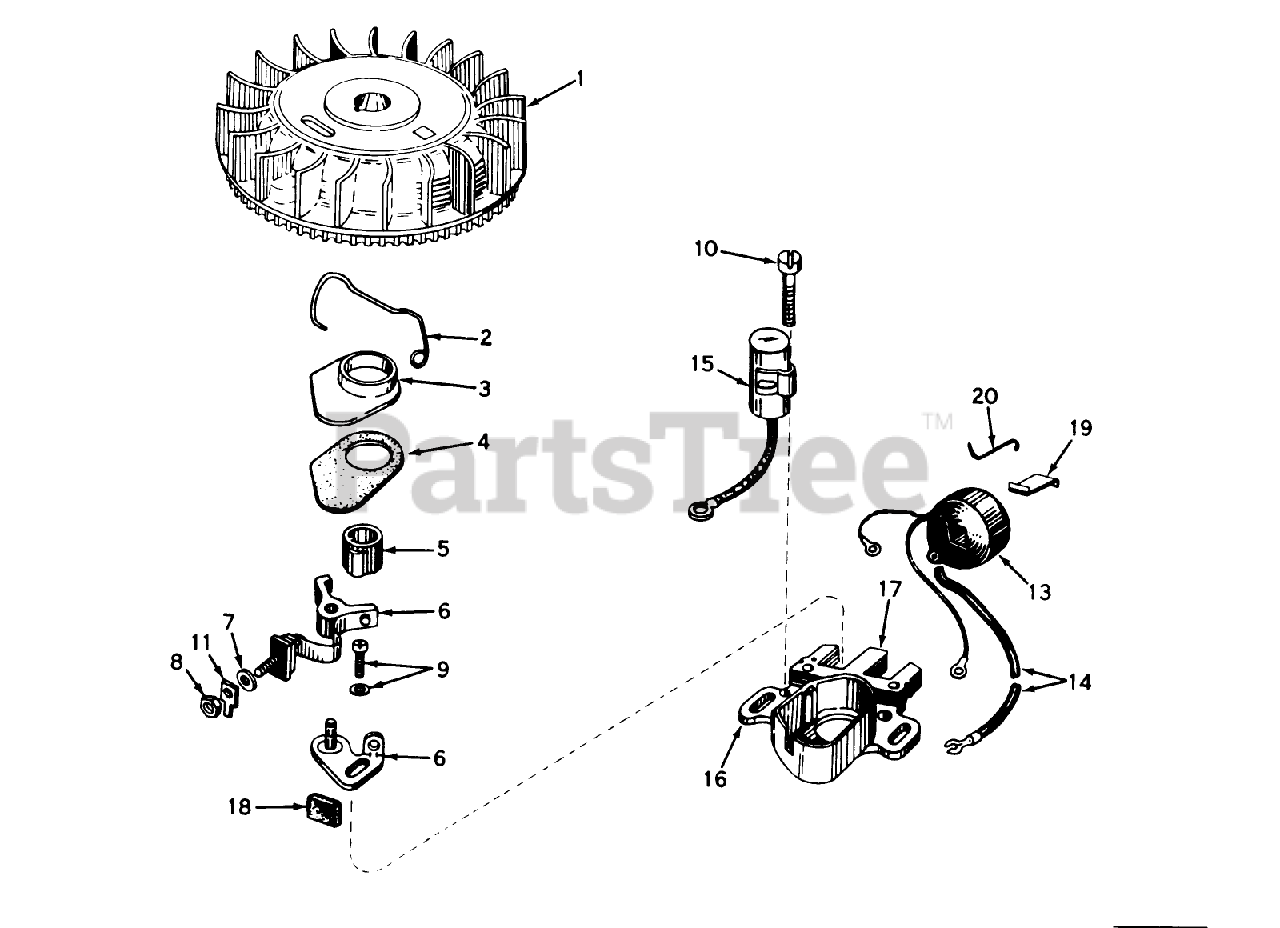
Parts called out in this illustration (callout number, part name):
1	Flywheel
2	Spring Breaker Box
3	Cover, Dust
4	Gasket Dust Cover
5	Cam-Breaker
6	Breaker Assy.
7	Washer
8	DECAL
9	Breaker Screw
10	Condenser Screw
11	Terminal, Ground
13	Coil Assy. (Incl. No. 12)
14	Wire, Lead
15	Condenser
16	Core Plate
17	Stator Assy., (Incl. Nos. 2, 3, 5 thru 14 16 thru 19)
18	Felt,Cam Wiper
19	Spring Coil Wedge
20	Clip, Coil
